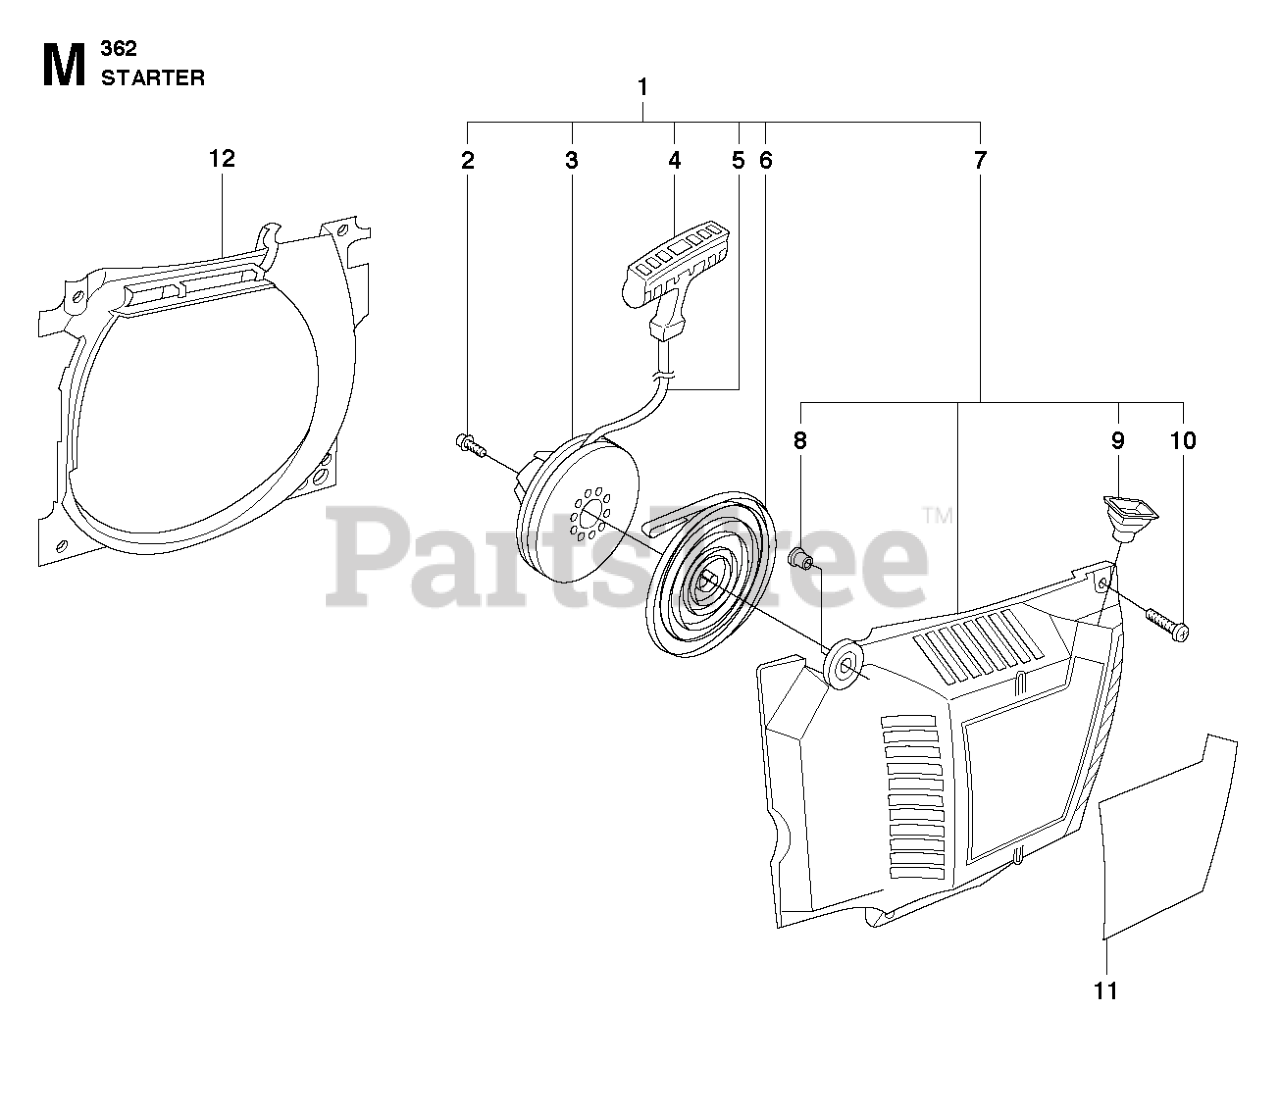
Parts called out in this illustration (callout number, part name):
1	STARTER ASSY
2	SCREW
3	STARTER PULLEY
4	STARTER HANDLE
5	STARTER CORD
6	SPRING
7	STARTER HOUSING
8	BUSHING
9	SLEEVE
10	SCREW.CIHPANMO M5X19 10.9
12	AIR CONDUCTOR
